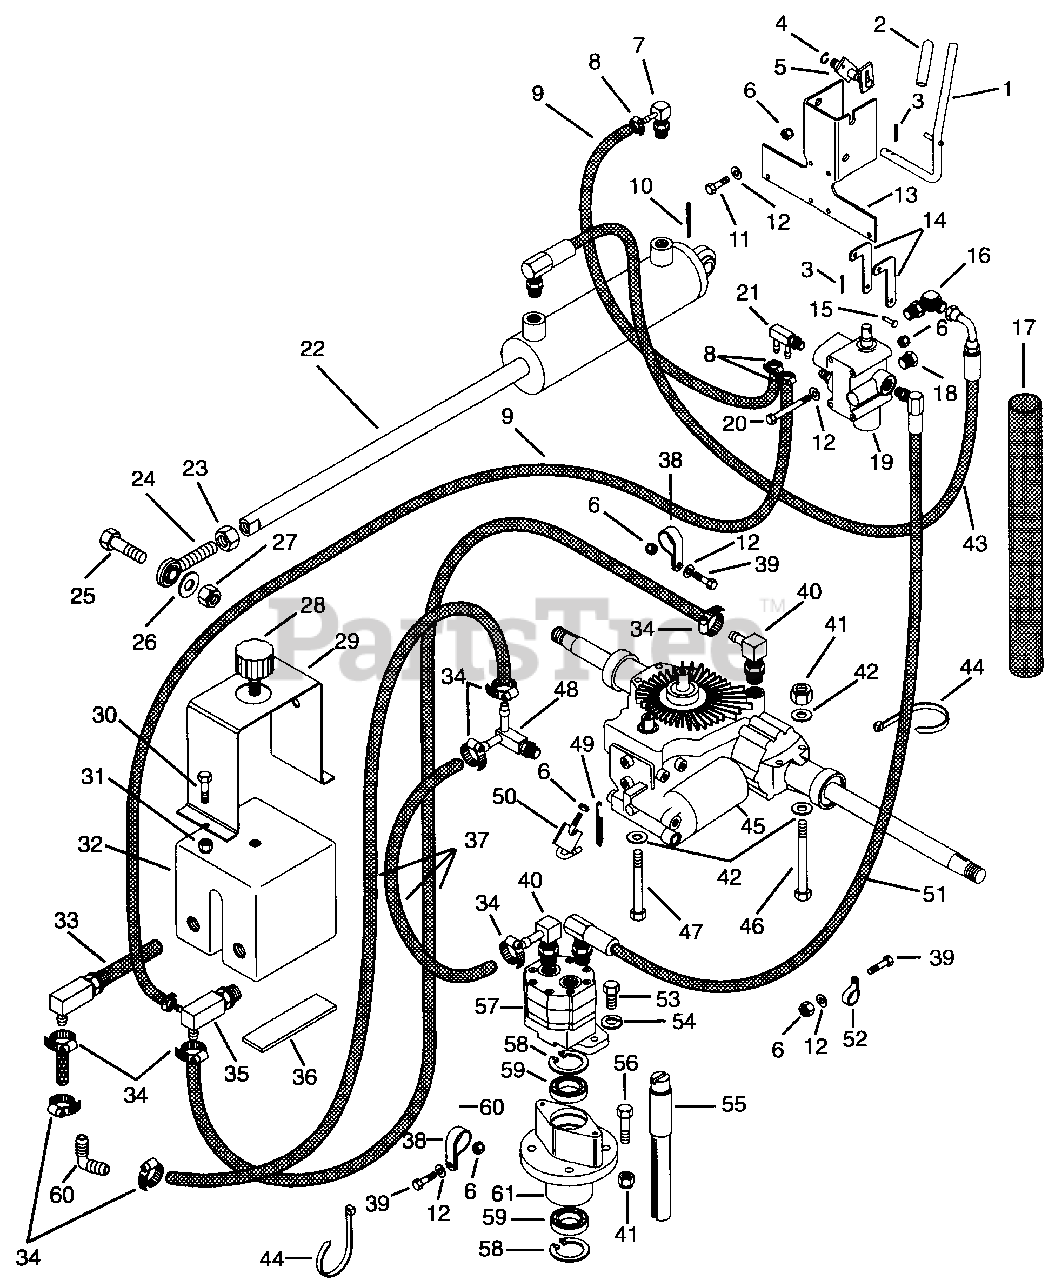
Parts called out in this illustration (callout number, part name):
1	Weldment, Lever
2	Grip, PTO Lever
3	Pin-Cotter .09 x .75
4	Ring-Retaining-External .392 x .042
5	Weldment, Linkage
6	Nut-Locking-Center .25-20
7	Fitting Adapter .562-18
8	Clamp-Hose .78 x .44 x 1.17
9	Hose, Hydraulic
10	Pin-Cotter .12 x 1.25
11	Bolt-Hex .25-20 x .75 Grade 5
12	Washer-Flat-Steel .281 x .620 x .065
13	Bracket
14	Lift Link
15	Pin-Clevis .188 x 1.00
16	Adapter 2503-6-4
17	Sleeve, Protective
18	Plug .44-20
19	Valve, Hydraulic
20	Bolt-Hex .25-20 x 3.00
21	Fitting-Pipe .563-18
22	Cylinder
23	Nut-Jam .50-20 Grade 2
24	Assembly, Rod End (Right Hand)
25	Bolt-Hex .50-13 x 1.50 Grade 5
26	Washer-Flat-Steel .50 x 1.25 x .083
27	Nut-Locking-Center .50-13
28	Cap, Filter
29	Strap, Tank
30	Bolt-Hex .31-18 x .75 Grade 5
31	Nut-Locking-Center .31-18
32	Tank Hydraulic
33	Fitting, Filter
34	Clamp, .88 Dia. Hose
35	Fitting with O-Ring 88-14 x .268
36	Pad, Gas Tank
37	Hose
38	Clamp, Steel 1.0
39	Bolt-Hex .25-20 x .75 Grade 5
40	Fitting
41	Nut-Locking-Nylon .375-16
42	Washer
43	Assembly, Pressure Hose
44	Tie Wrap, Black
45	Filter, Oil
46	Bolt-Hex .38-16 x 4.00 Grade 5
47	Bolt-Hex .38-16 x 3.25 Grade 5
48	Fitting-Pipe .875-14
49	Spring-Tension .061 x .50 x 3.5
50	Weldment Lever
51	Assembly, Pressure Hose
52	Clamp, Cushioned Steel
53	Bolt-Hex .38-16 x .75 Grade 5
54	Washer-Locking .38 x .094
55	Shaft
56	Bolt-Hex .38-16 x 1.50 Grade 5
57	Pump, Hydraulic
58	Ring-Retaining-Internal 2.210 x .062
59	Bearing-Ball 1.0 x 2.0 x .56
60	Elbow-Barbed .63 x .63
61	Housing
